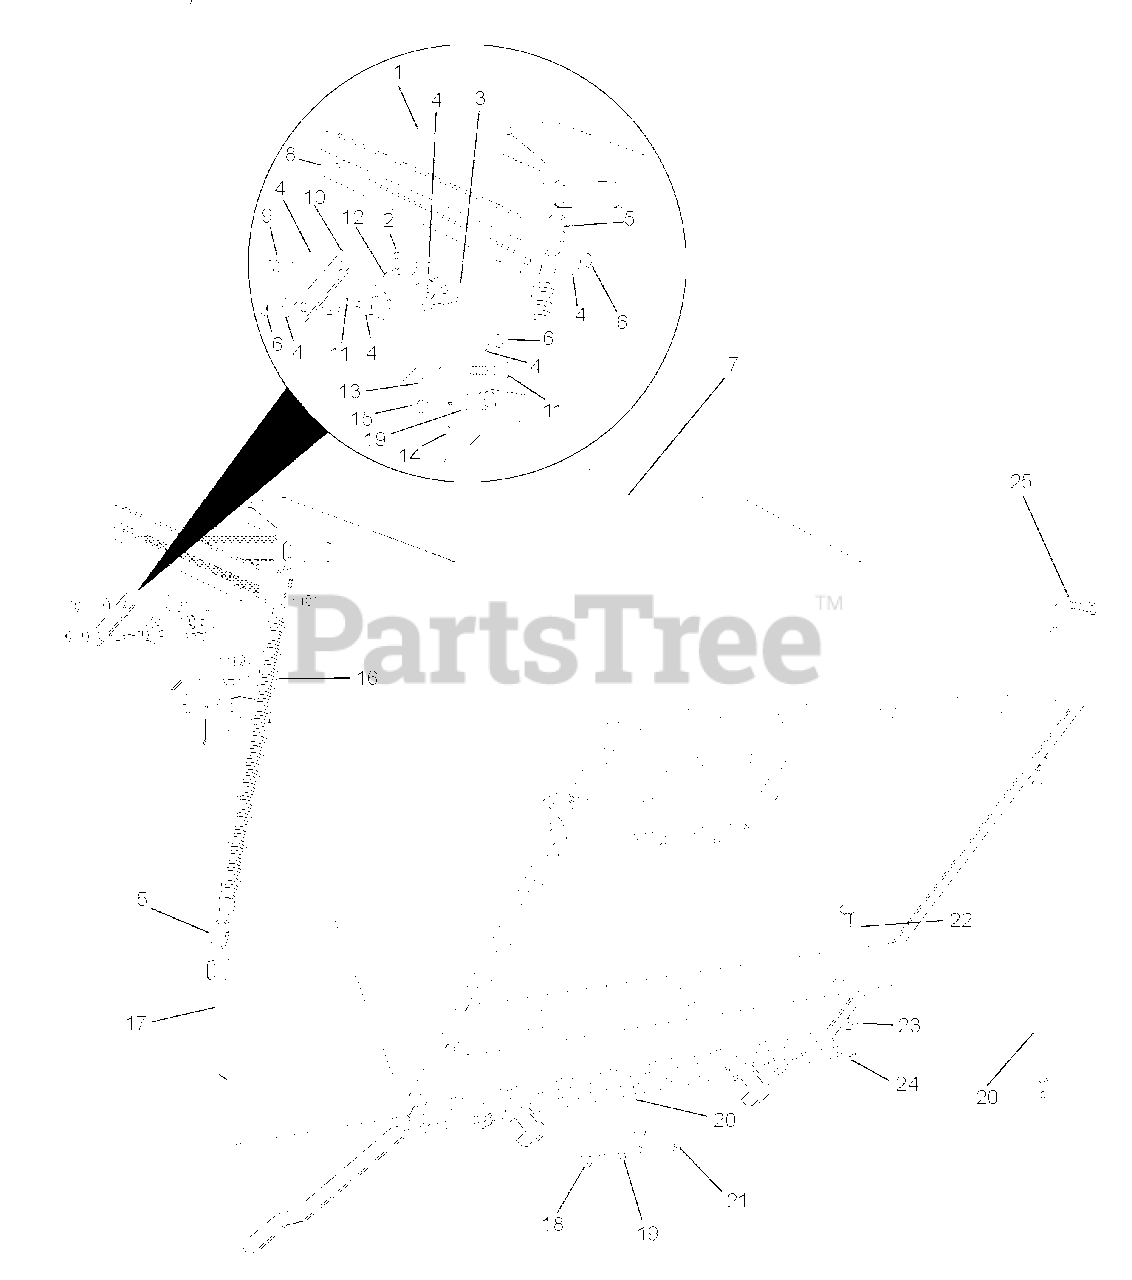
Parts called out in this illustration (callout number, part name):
1	Weldment, Grid
2	Link Spacer, Screen Door
3	Weldment, Screen Door
4	Washer, Flat .312
5	Quick Link .25
6	Nut, Hex Lock .312-18
7	Weldment, Hopper
8	Screen, Single (995420, 430)
9	Cap Screw, Hex Head .312-18 x 1.50
10	Linkage, Filter Door
11	Cap Screw, Flat Countersunk Head Hex Socket .312-18 x 1.00
12	Latch, Filter Door Right Hand
13	Gasket Material .75 x .25
14	Pin, Cotter Stainless Steel .125 x .75
15	Pin, Clevis .38 x 1.125
17	Weldment, Door
18	Cap Screw, Hex Head .38-16 x 1.00
19	Washer, Flat .38
20	Brace, Hopper
21	Nut, Lock .38-16
22	Bolt, Carriage .50-13 x 1.50
23	Washer, Flat .50
24	Nut, Lock .50-13
25	Cap Screw, Hex Head .38 x .75
